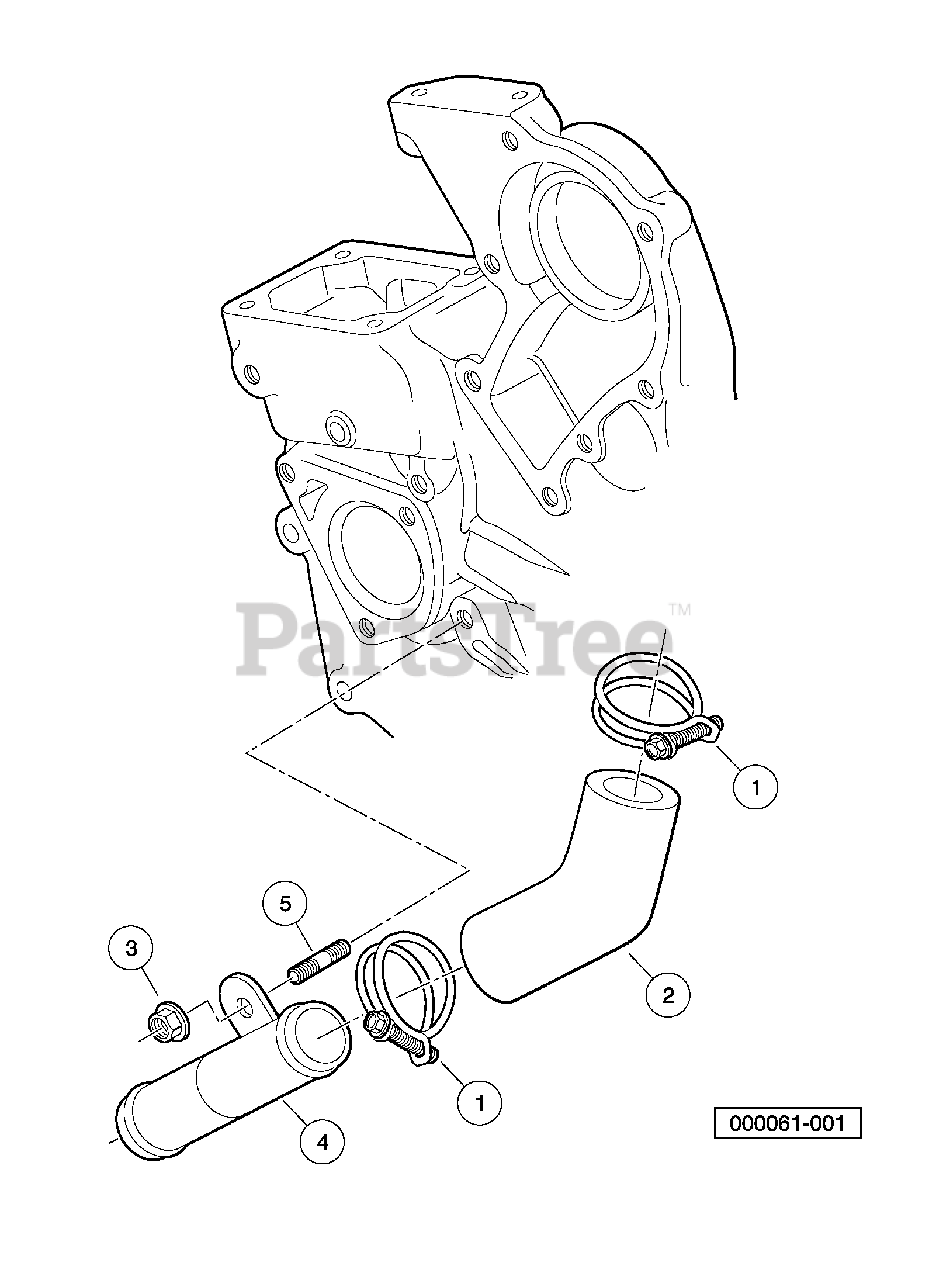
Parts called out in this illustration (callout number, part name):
1	Band, Pipe, with Nut
2	Pipe, Water, Bent
3	Nut, Flange, M6
4	Pipe, Water, Bent
5	Stud, M6 X 15
